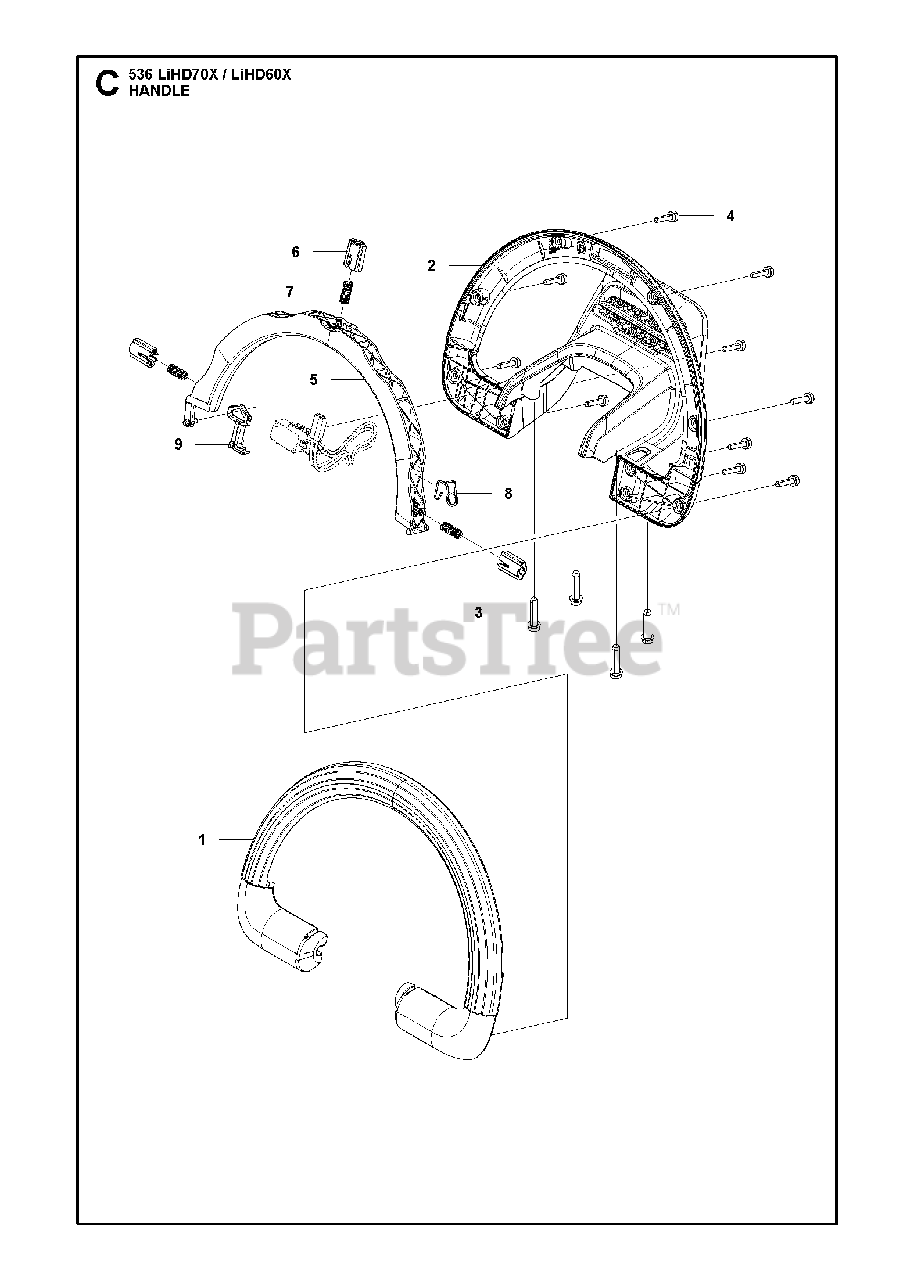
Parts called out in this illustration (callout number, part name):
1	FRONT HANDLE COVER
2	FRONT HANDLE HANDGUARD
4	SCREW
5	FRONT HANDLE LOCKOUT
6	BUSHING FRONT HANDLE
7	RECOIL SPRING FRONT HANDLE
8	SPRING FRONT HANDLE
9	LEVER FRONT HANDLE
